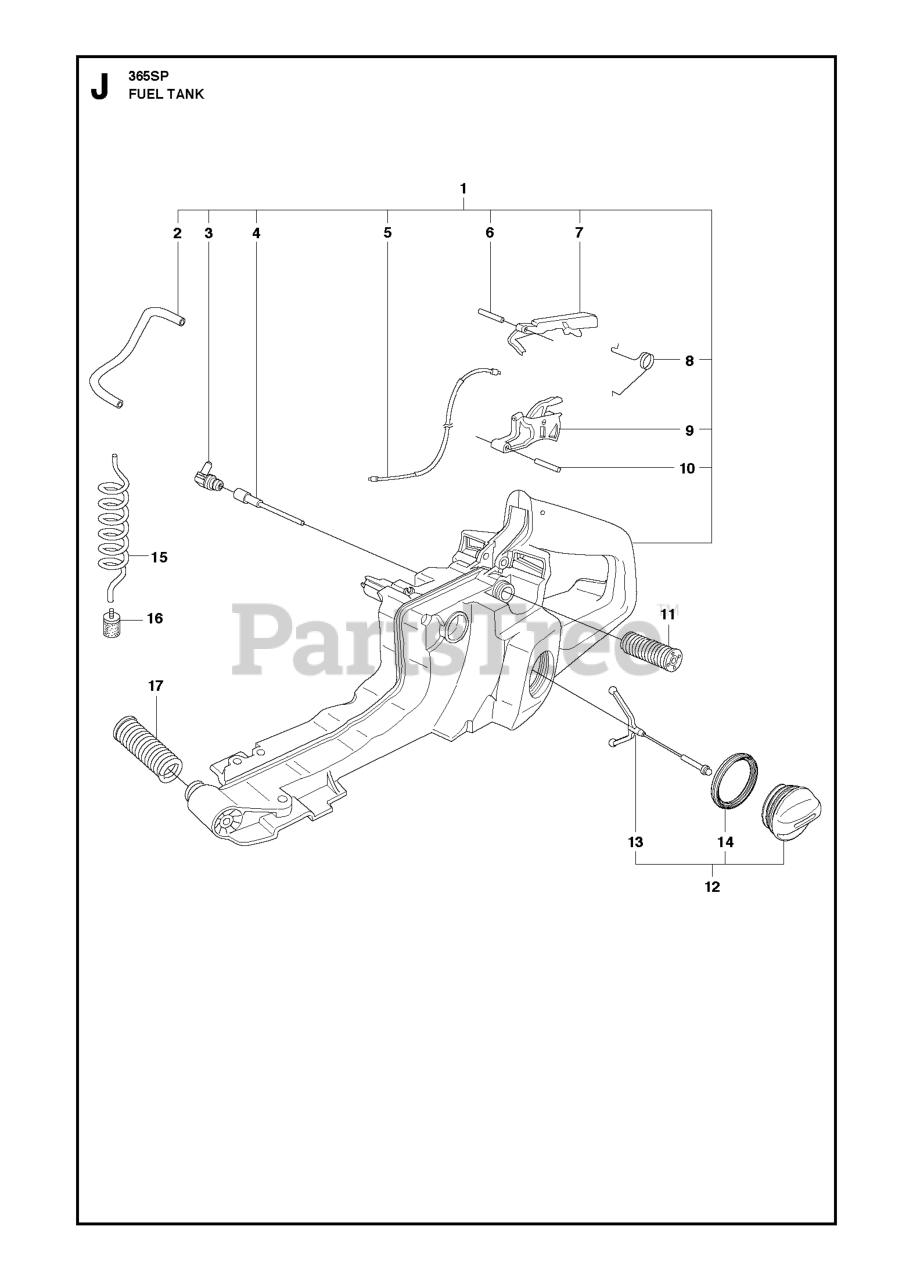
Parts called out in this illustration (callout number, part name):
1	TANK/HANDLE ASSY
2	HOSE
4	TANK VALVE
6	PIN 3X25
7	THROTTLE CATCH
9	THROTTLE TRIGGER
10	PIN CPH8 4X20
11	ANTIVIBE MOUNT
12	TANK CAP
15	FUEL HOSE
16	RP FUEL FILTER
17	AV SPRING (HARD)
17	ANTIVIBE MOUNT
